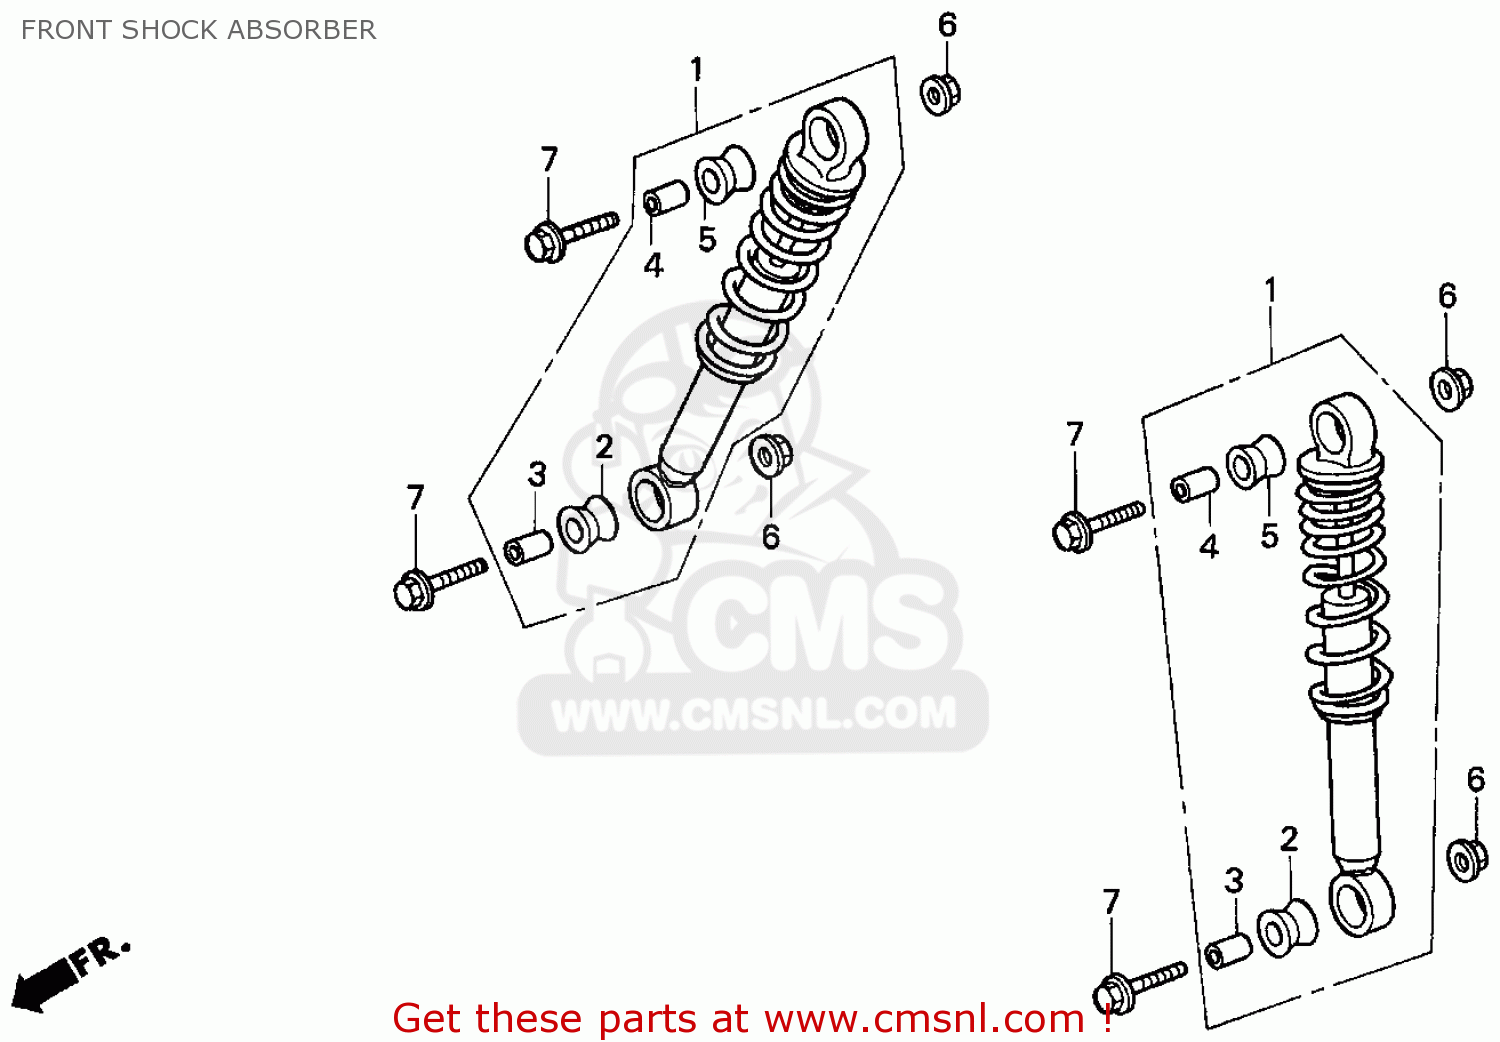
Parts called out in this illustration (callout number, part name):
1	CUSHION ASS*R134*
2	BUSH,RUBBER
3	COLLAR,RUB.BUSH
4	COLLAR, CUSHION
5	BUSH, CUSHION
6	NUT,SELF LOCK,10M
7	BOLT,FLANGE,10X40
